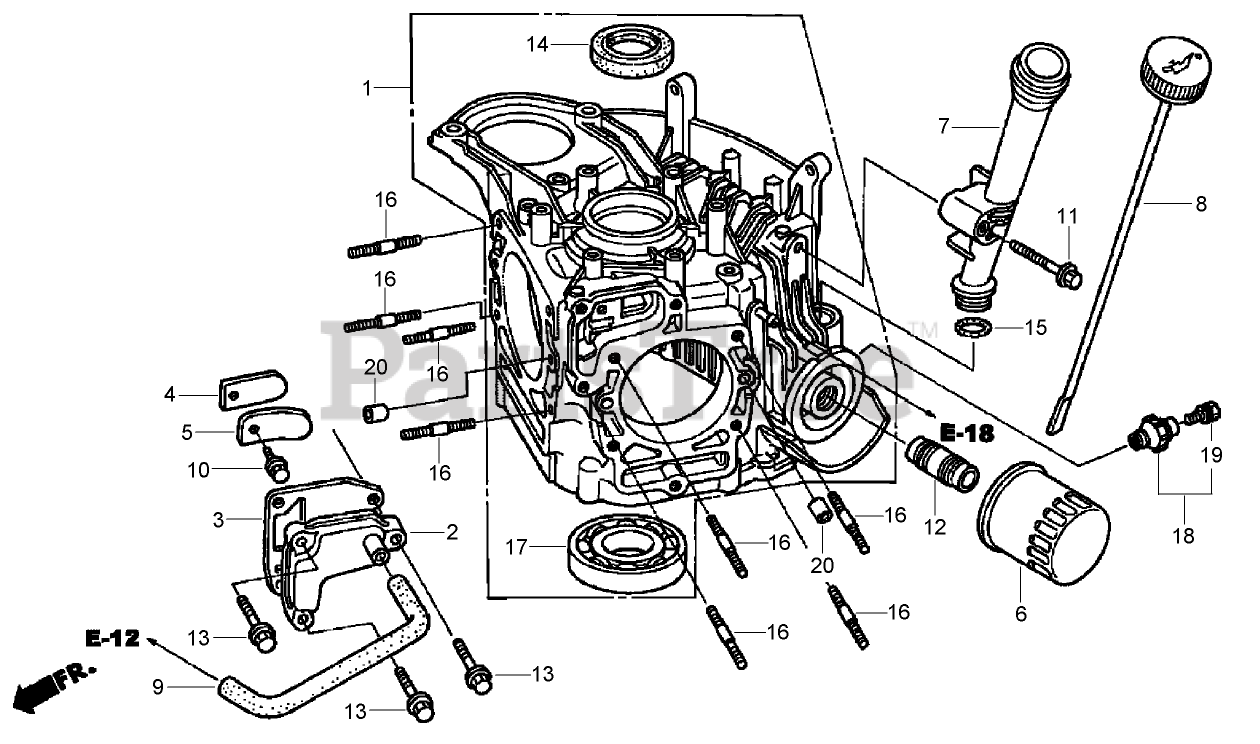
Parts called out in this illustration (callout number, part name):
1	CRANKCASE ASM (840)
2	COVER-BREATHER
3	GASKET-COVER, BREATHER
4	PLATE-VALVE
5	STOPPER-VALVE
6	FILTER-OIL (TOYO ROKI)
7	EXTENSION-FILLER, OIL
8	DIPSTICK-OIL
9	TUBE-BREATHER
10	BOLT-FLANGE (5X10)
11	BOLT-FLANGE (6X45) (C T200)
12	HOLDER-FILTER, OIL
13	BOLT-FLANGE (6X25) (C T 200)
14	SEAL-OIL (35X5X8)
15	O-Ring (22.5X2.2)
16	BOLT-STUD (8X28)
17	BEARING-BALL, RADIAL
18	OIL PRESSURE SWITCH ASM
19	BOLT-WASHER (4X8) (DENSO)
20	Pin-Dowel (8X14)
